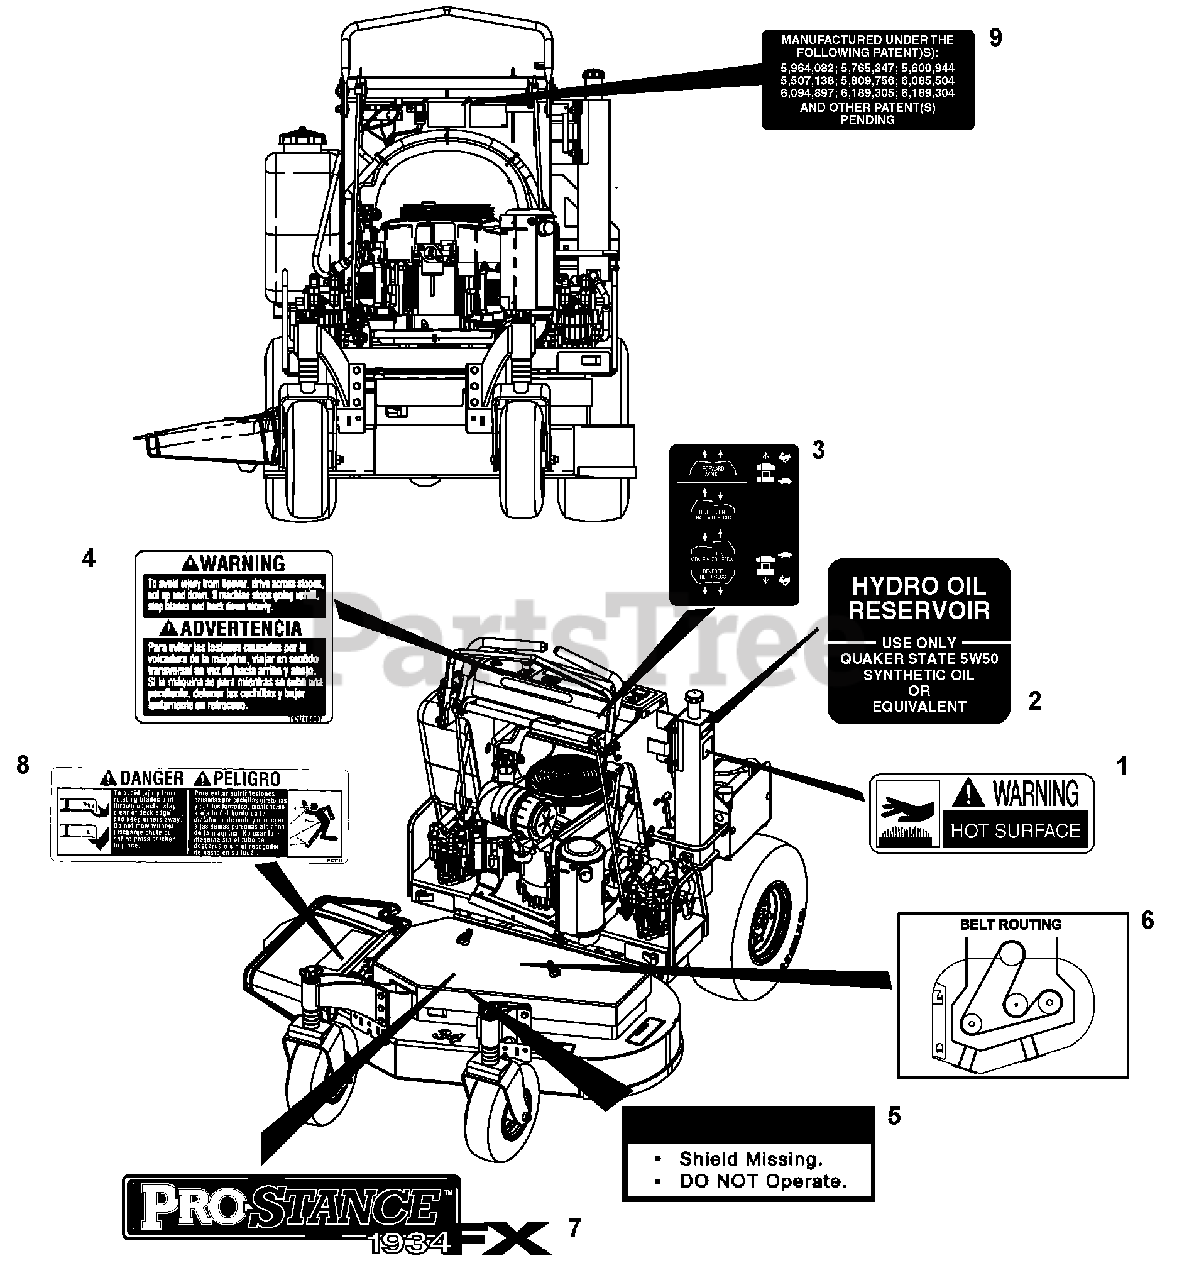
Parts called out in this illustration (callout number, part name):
1	Decal, Warning, Hot Surface
2	Decal, Hydro Oil Reservoir
3	Decal, Directional Control
4	Decal, Danger - Avoid Tipover
5	Decal, Belt Path
6	Decal, Warning, Shield
7	Decal, Pro-Stance 1934FX
8	Decal, Danger - Thrown Objects
9	Decal, Patent
